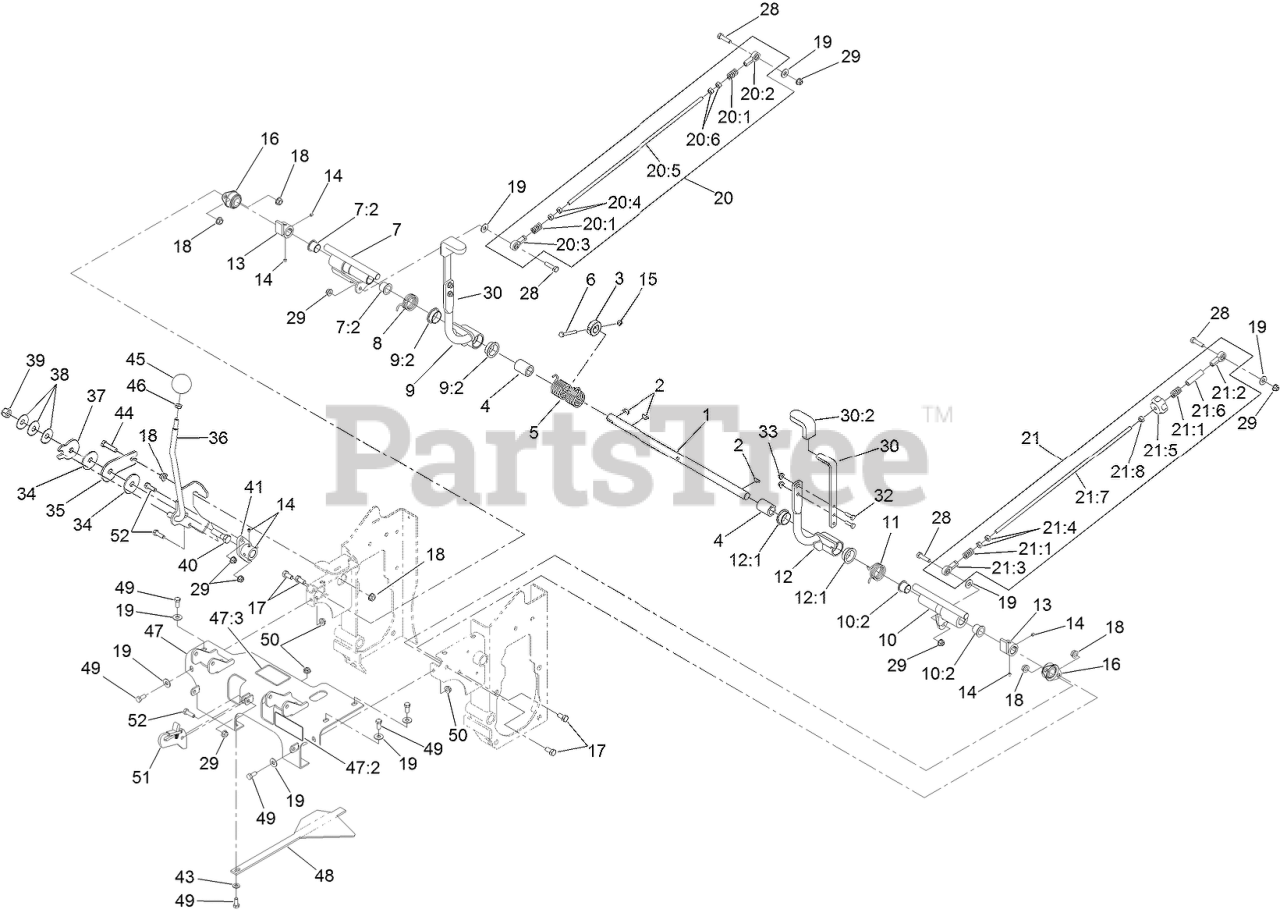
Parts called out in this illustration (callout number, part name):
1	SHAFT-CONTROL, SPEED
2	KEY-WOODRUFF
3	STOP-HUB, CENTER
4	BUSHING-PLASTIC
5	SPRING-TORSION, DOUBLE
6	SCREW-HH
7	RH CONTROL HUB ASM
7:2	BEARING-FLANGE, IGLIDE
8	SPRING-TORSION, RH
9	RH STEERING HANDLE ASM
9:2	BEARING-FLANGE, IGLIDE
10	LH CONTROL HUB ASM
10:2	BEARING-FLANGE, IGLIDE
11	SPRING-TORSION, LH
12	LH STEERING HANDLE ASM
12:1	BEARING-FLANGE, IGLIDE
13	HUB-SPEED CONTROL
14	SCREW-SET
15	NUT-LOCK, NI
16	BEARING-FLANGE, SIDE
17	SCREW-HH
18	NUT-HHF, WHIZ
19	WASHER-FLAT
20	RH PUMP LINKAGE ASM
20:1	SPRING-COMPRESSION
20:2	BALLJOINT-RH
20:3	BALLJOINT-LH
20:5	ROD-LINKAGE, STEERING
20:6	NUT-HEX
21	LH PUMP LINKAGE ASM
21:1	SPRING-COMPRESSION
21:2	BALLJOINT-RH
21:3	BALLJOINT-LH
21:5	KNOB-TRACKING
21:7	ROD-LINKAGE, STEERING
21:8	NUT-HEX
28	SCREW-HH
29	NUT-HF, NI
30	HANDLE ASM
30:2	GRIP-HANDLE, STEERING
32	SCREW-HH
34	DISC-FRICTION
35	PLATE-FRICTION, SPEED CON
36	LEVER-SPEED CONTROL
37	PLATE-FRICTION, SPEED CON
38	WASHER-DISC, SPRING
39	NUT-HEX
40	SCREW-HH
41	HUB-CONTROL, SPEED
43	WASHER-PLAIN
44	SCREW-HH
45	KNOB-BALL, SPEED CONTROL
46	NUT-JAM
47	CONSOLE ASM
47:2	DECAL-DANGER, DRIVELINE
47:3	Decal-Motor, Wheel
48	GUIDE-PLENUM
49	SCREW-HH
52	SCREW-HH
